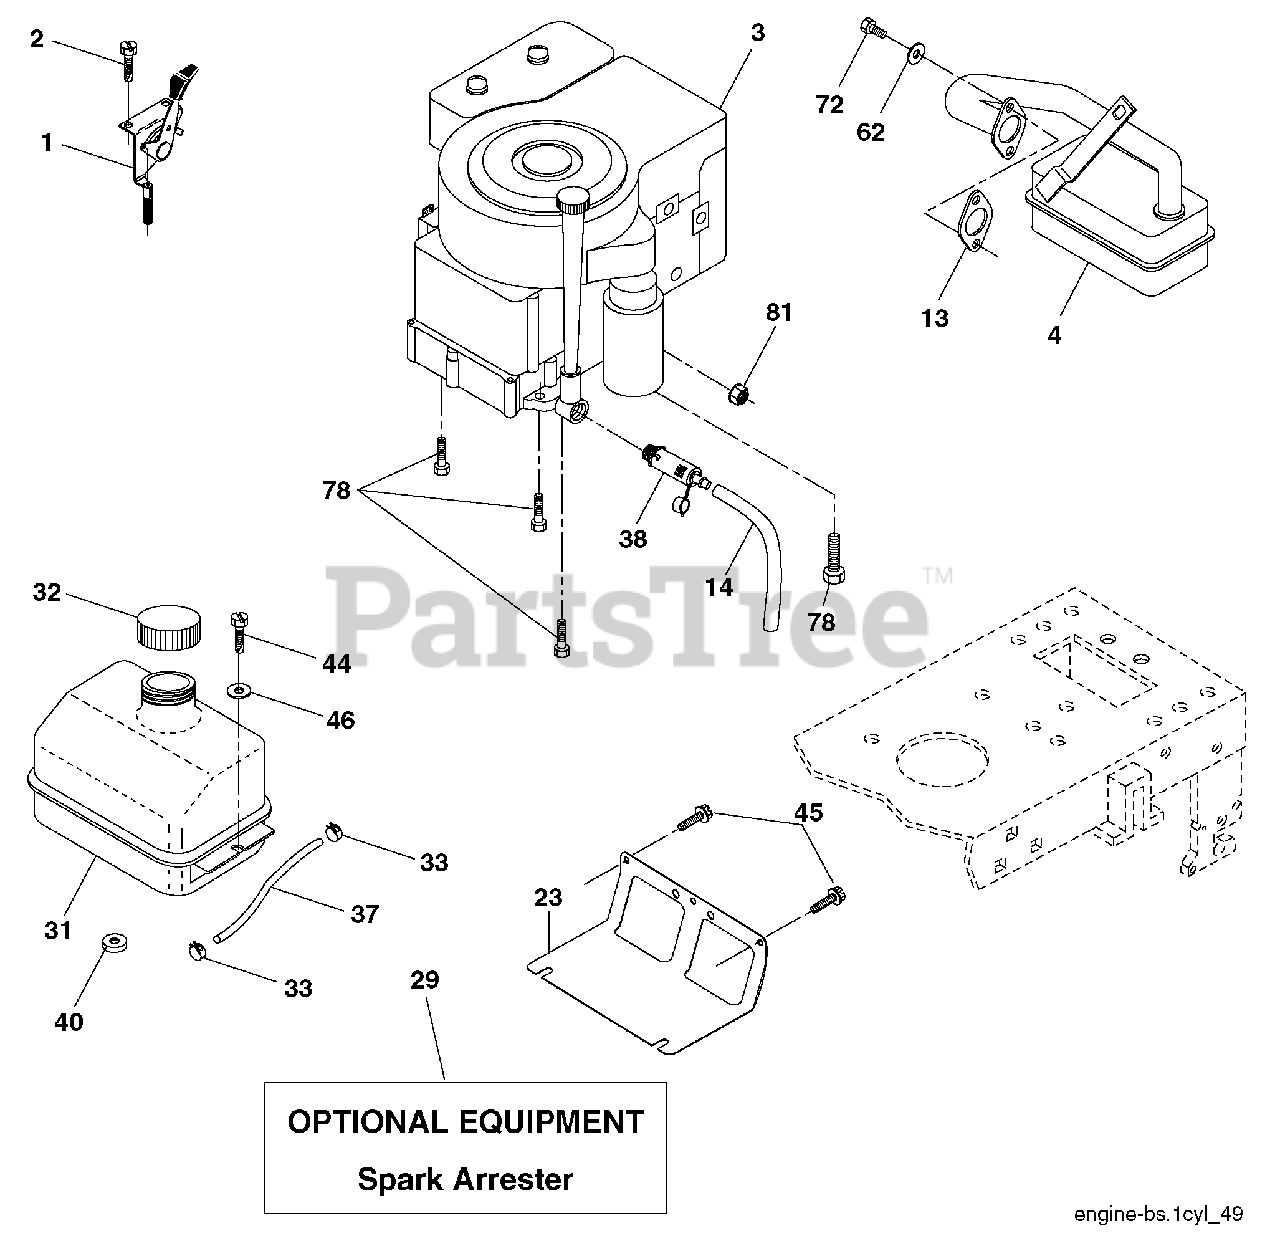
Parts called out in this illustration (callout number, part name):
1	Control Th/ch Flag
2	Screw Hex Thd Cut 1/4-20 x 1/2
4	Muffler Exhaust B&S
13	Gasket Eng 1 313 Id Tin Plated
14	Tube Drain Oil Easy
23	Shield BRN/DBR Guard
29	Kit Spark Arrestor (Flat Scrn)
31	Tank Fuel Front
32	Cap Asm Fuel
33	Clamp Hose
37	Line Fuel 20"
38	Plug Drain Oil
40	Bushing Snap Nyl Blk Fuel Line
44	Screw Thdrol 1/4-20 x 3/4
45	Screw Hex Wsh Thdrol 3/8-16
46	Washer 9/32 x 7/8 x 16 Ga.
62	Washer Split
72	Screw Socket Head 5/16-18 x 3/4
78	Screw 3/8-16 x 1-1/4
81	Nut Keps Hex 1/4-20 unc
